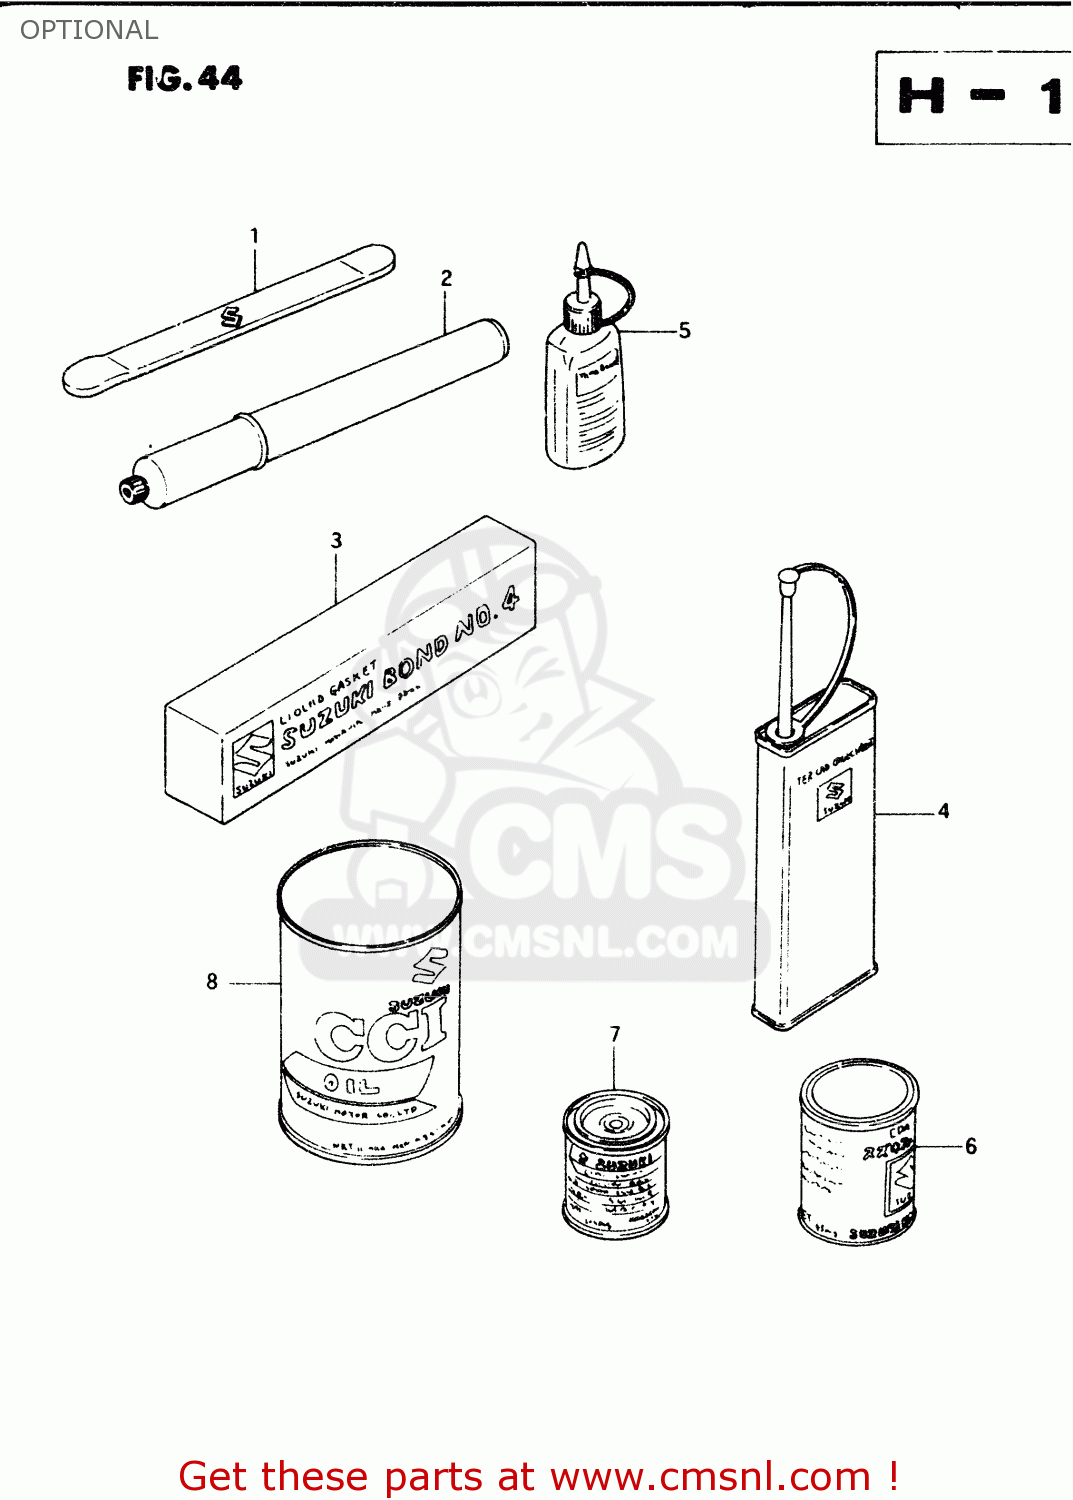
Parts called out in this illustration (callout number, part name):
1	LEVER,TIRE
2	INFLATOR, AIR
3	BOND 1104
4	THREAD LOCK NO.1401 CLEAR 200G
5	THREAD LOCK NO
6	GREASE(C)EP2 LITHIUM 150G
7	PAINT,BLACK
8	CCI OIL
